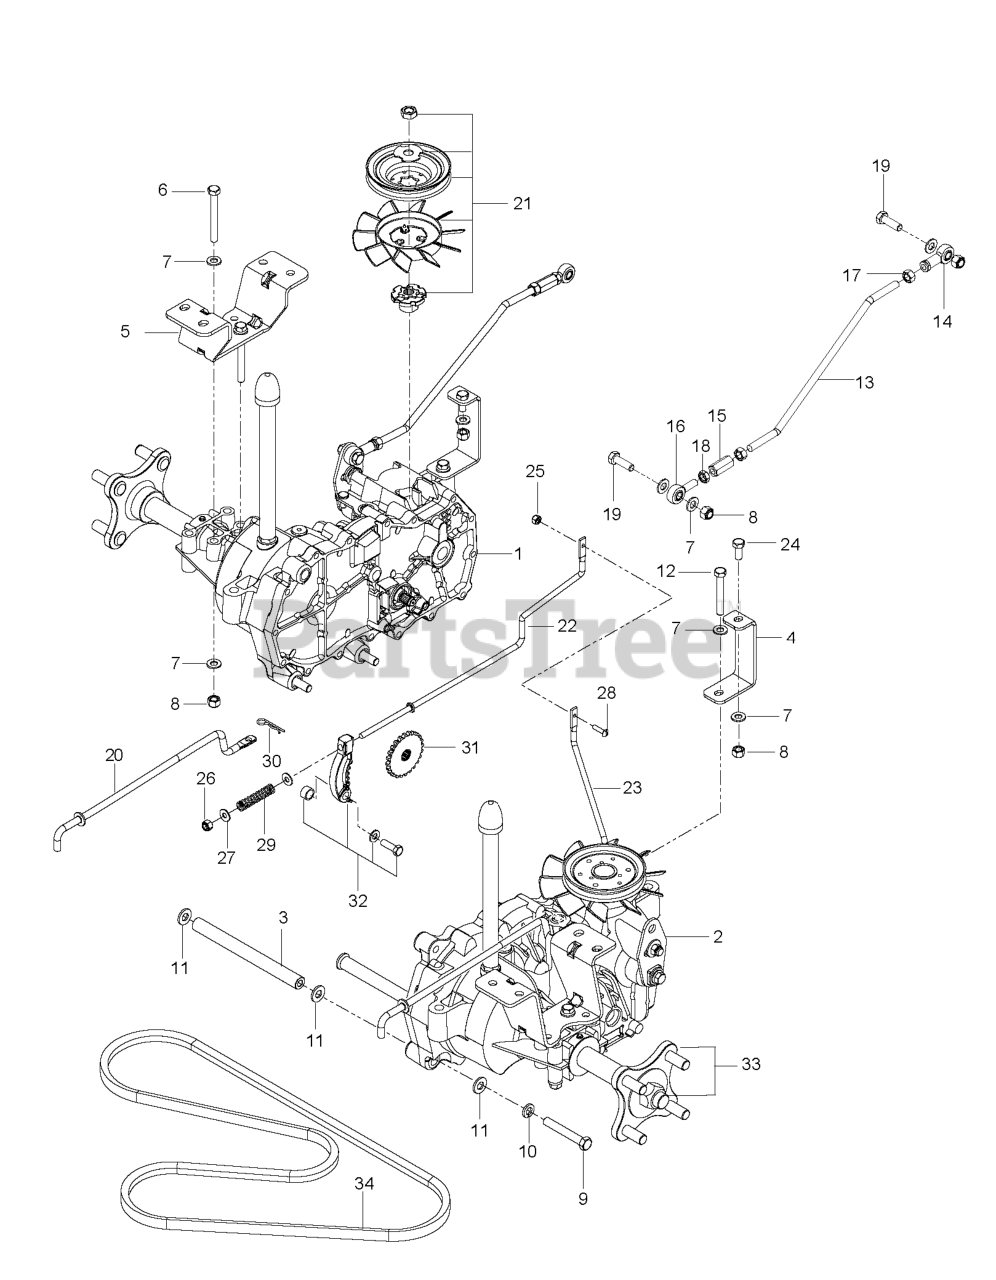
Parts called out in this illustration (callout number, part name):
1	HG_EZT, LT
2	HG_EZT, RT
3	SPACER TUBE, EZT
4	SUPPORT.FRONT.TRANS.BLACK.
5	EZT MOUNT, REAR, BLACK
6	HCS 5/16C X 2-3/4
7	FLAT WASHER 5/16 SAE
8	NUT 5/16 NYLOC
9	HCS 3/8C X 2 1/2
10	SLW 3/8 STD
11	WASHER 3/8 SAE FLAT
13	RP.ROD, MOTION CONTROL
14	RH ROD END
15	ROD END COUPLER
16	RP.ROD.END.LH
18	NUT 5/16F LEFTHAND
19	HCS 5/16C X 1
20	LINKAGE, BYPASS, EZT
21	KIT FAN/PULLEY 72137
22	LINKAGE, BRAKE, LT
23	LINKAGE, BRAKE RT
24	HCS 5/16C X 3/4
25	NUT 10-24 NYLOC
26	NUT.1/4-20.HEX.NYLOC.ZD
27	WASHER 1/4 SAE
28	SCR #10-24 X 3/4
30	HAIRPIN #2
31	HG_DISC COG BRAKE 51635
32	HG_KIT BRAKE ARM (EZT)
33	HUB KIT (H-G #70314)
34	BELT, HYDRO PUMP
